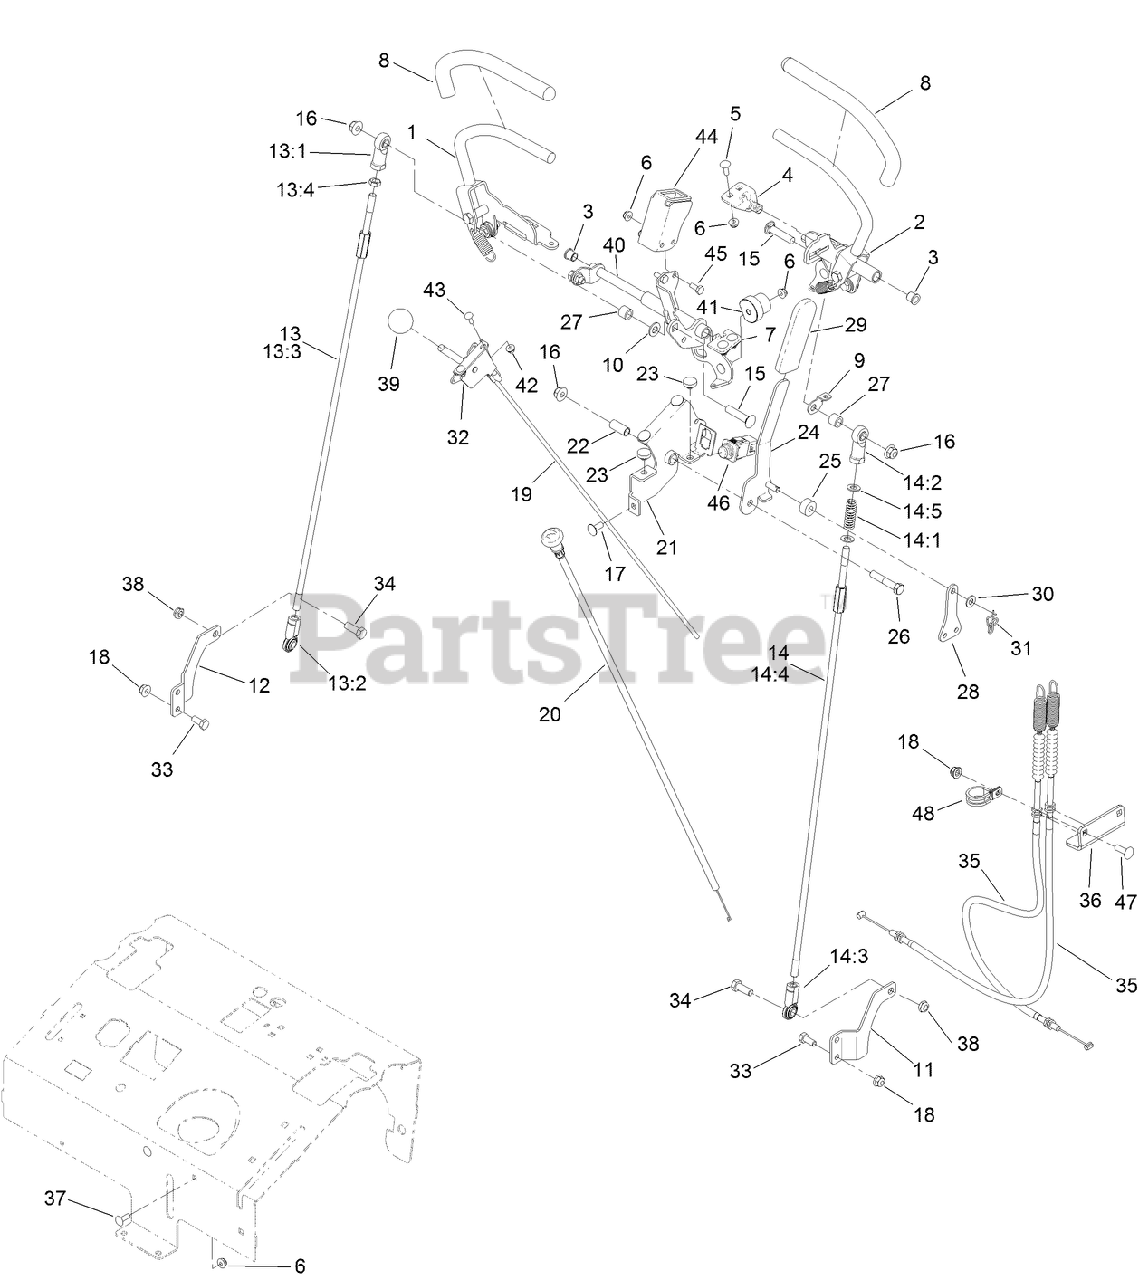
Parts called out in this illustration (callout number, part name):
1	RH CONTROL HANDLE ASM
2	LH CONTROL HANDLE ASM
3	BEARING
4	TAB-PIVOT, LH
5	BOLT-CARR
6	NUT-HF
7	TAB-PIVOT, RH
9	BRACKET-ADJUSTMENT, SPEED
10	WASHER-FLAT
11	BRACKET-HYDRO, LH
12	BRACKET-HYDRO, RH
13	RH CONTROL ROD ASM
13:1	END-ROD, FEMALE
13:2	JOINT-BALL END, LH
13:3	ROD-CONTROL
13:4	NUT-HJ
14	LH CONTROL ROD ASM
14:1	SPRING-RETURN, NEUTRAL
14:2	END-ROD, FEMALE
14:3	JOINT-BALL END, LH
14:4	ROD-CONTROL
14:5	WASHER-FLAT
15	SCREW-CARR
16	NUT-HF, NI
17	SCREW-CARR
18	NUT-HF, NI
19	CABLE-CONTROL
20	CABLE-CHOKE
21	BRACKET-BRAKE, PIVOT
22	BEARING-SLEEVE
23	BUMPER
24	HANDLE-ARM, BRAKE
25	BUSHING-BRAKE
26	SCREW-HH
27	SPACER
28	YOKE-CABLE
29	GRIP-LEVER
30	SPACER-NYLON
31	PIN-COTTER
32	LEVER-CONTROL
33	SCREW-HH
34	SCREW-HH
35	CABLE-BRAKE
36	BRACKET-CABLE, BRAKE
39	KNOB-BALL
40	PIVOT/PLATE SWITCH ASM
42	NUT-LOCK, FLANGE
43	BOLT-CARR
44	BRACKET-SWITCH
45	SCREW-HH
46	SWITCH-PLUNGER
47	SCREW-CARR
48	CLAMP-R
